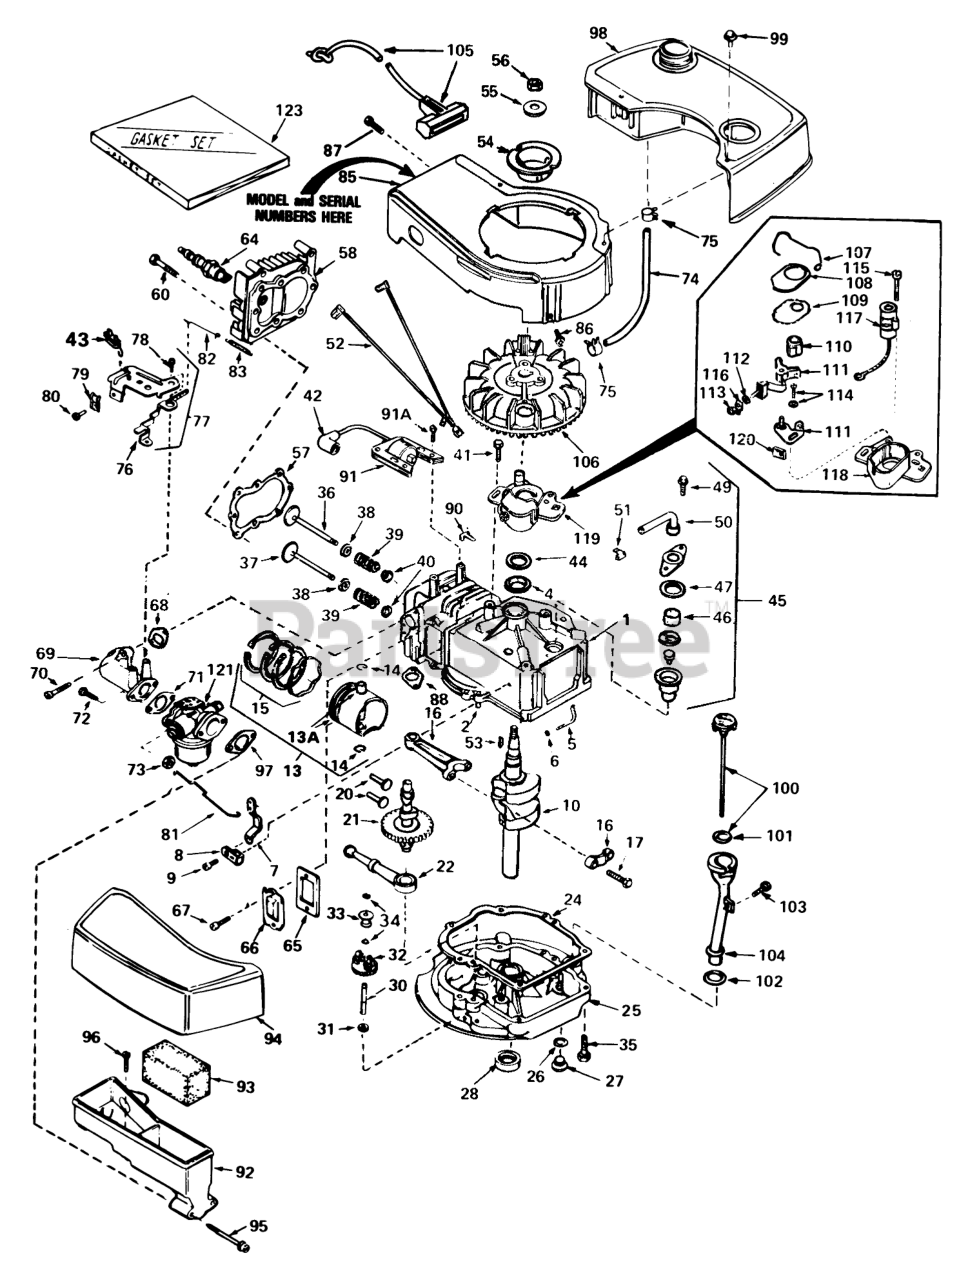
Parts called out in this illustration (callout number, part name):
1	Cylinder Assy. (Incl. Ref. #2 & 4)
2	Pin-Dowel
4	Seal-Oil
5	Rod, Governor (Incl. Ref. #6)
6	Washer-Flat
7	Governor Lever
8	Clamp-Lever, Governor
9	Screw
10	Crankshaft
13	Piston, Pin & Ring Assy. (Incl.Ref. #13A, 14 & 15) (Std.)
13	Piston, Pin & Ring Assy.(Incl. Ref. #13A, 14 & 15)(.010 Oversize)
13	Piston, Pin & Ring Assy.(Incl. Ref. #13A, 14 & 15)(.020 Oversize)
13A	Piston & Pin Assy (Incl. Ref. #14)(Std.)
13A	Piston & Pin Assy. (Incl. Ref. #14)(.010 Oversize)
13A	Piston & Pin Assy. (Incl. Ref. #14)(.020 Oversize)
14	Ring-Retaining, Piston Pin
15	Ring Set Piston (Std.)
15	Ring Set Piston (.010 Oversize)
15	Ring Set Piston (.020 Oversize)
16	Rod Assy., Connecting(Incl. Ref. #17)
17	Bolt-Rod, Connecting
20	Lifter-Valve
21	Camshaft(Mech.Comp. Release)
22	Oil Pump ASM
24	Gasket, Mounting
25	Flange Assy., Mounting(Incl. Ref. #26 thru 30)
26	Gasket-Oil Drain
27	Plug Oil Drain
28	Seal Oil
30	Shaft-Governor
31	Washer-Flat
32	Gear Assy., Governor (Incl. Ref. #31)
33	Spool-Governor
34	Ring-Retaining
35	Screw (1/4-20 x 1-1/4)
36	Valve, Intake (Std.)(Incl. Ref. #38, 39 & 40)
36	Valve, Intake ( 1/32" Oversize)(Incl. Ref. #38, 39 & 40)
37	Valve, Exhaust (Std.)(Incl. Ref. #38, 39 & 40)
37	Valve, Exhaust ( 1/32" Oversize)(Incl. Ref. #38, 39 & 40)
38	Cap-Upper Valve Spring
39	Spring-Valve
40	Cap-Valve, Spring
42	Cover-Spark Plug
43	Terminal
44	Gasket Stator
45	Breather Assy. (Incl. Ref. #46, 47, 49, 50 & 51 )
46	Element-Breather
47	Gasket-Breather
49	Screw (10-24 x 9/16)
50	Tube, Breaker
51	Clip, Breather
52	Wire Ground
53	682488 LB GRASS HI-
54	Hub-Starter
55	Washer-Belleville
56	Nut-Flywheel
57	63573 GIL 42 SNWTHW
58	Head-Cylinder
60	Screw (5/16-18x1-1/2)
64	Plug, Spark (J17LM or equiv.)
64	Plug, Spark (Champion RCJ-8)
65	Gasket-Breather
66	Cover-Valve
68	Gasket-Intake
69	Pipe, Intake
70	Screw (1/4-20 x 1)
71	Gasket-Carburetor
72	Screw (1/4-28 x 7/8)
73	Nut and Lock Washer (1/4-28)
74	Line-Fuel
75	Clamp-Line, Fuel
76	Lever Control
77	Control Assy., Speed (Incl. Ref. #43, 76 & 78)
78	Screw, Hex Washer Hd Shoulder Self-Tap
79	Conduit
80	Screw (10-32 x 3/8)
81	Link-Throttle
82	Link Governor Spring
83	Spring Governor
85	Housing Blower
86	Screw
87	Screw (10-24 x 9/16)
88	Gasket Exhaust
90	Clip-Wire
91	Lamination & Coil Assy. (Incl. Ref. #42)
91A	Screw
92	Body Air Cleaner
93	Filer, Air
94	Cove, Air Cleaner
95	Screw Fil Hd.
96	Screw, Hex Hd.
97	Gasket-Air Cleaner
98	Tank, Fuel
99	Screw (10-32 x 35/64)
100	Dipstick, Oil (Incl. Ref. #101 )(Twist Lock)
103	Screw (10-32 x 1/2)
104	Tube-Oil Fill
105	Rope Assy., Starter
106	FIywheel
107	Spring Breaker Box
108	Cover-Dust
109	Gasket-Dust Cover
110	Cam-Breaker
111	Breaker Assy.
114	Breaker Screw
115	Condenser Screw
116	Terminal, Ground
117	Condenser
118	Stator Plate
119	Stator Plate Assy. (Incl. Ref. #107, 111 thru 118 & 120)
120	Felt,Cam Wiper
121	Carburetor (Incl. Ref. #71)
123	Gasket Set
